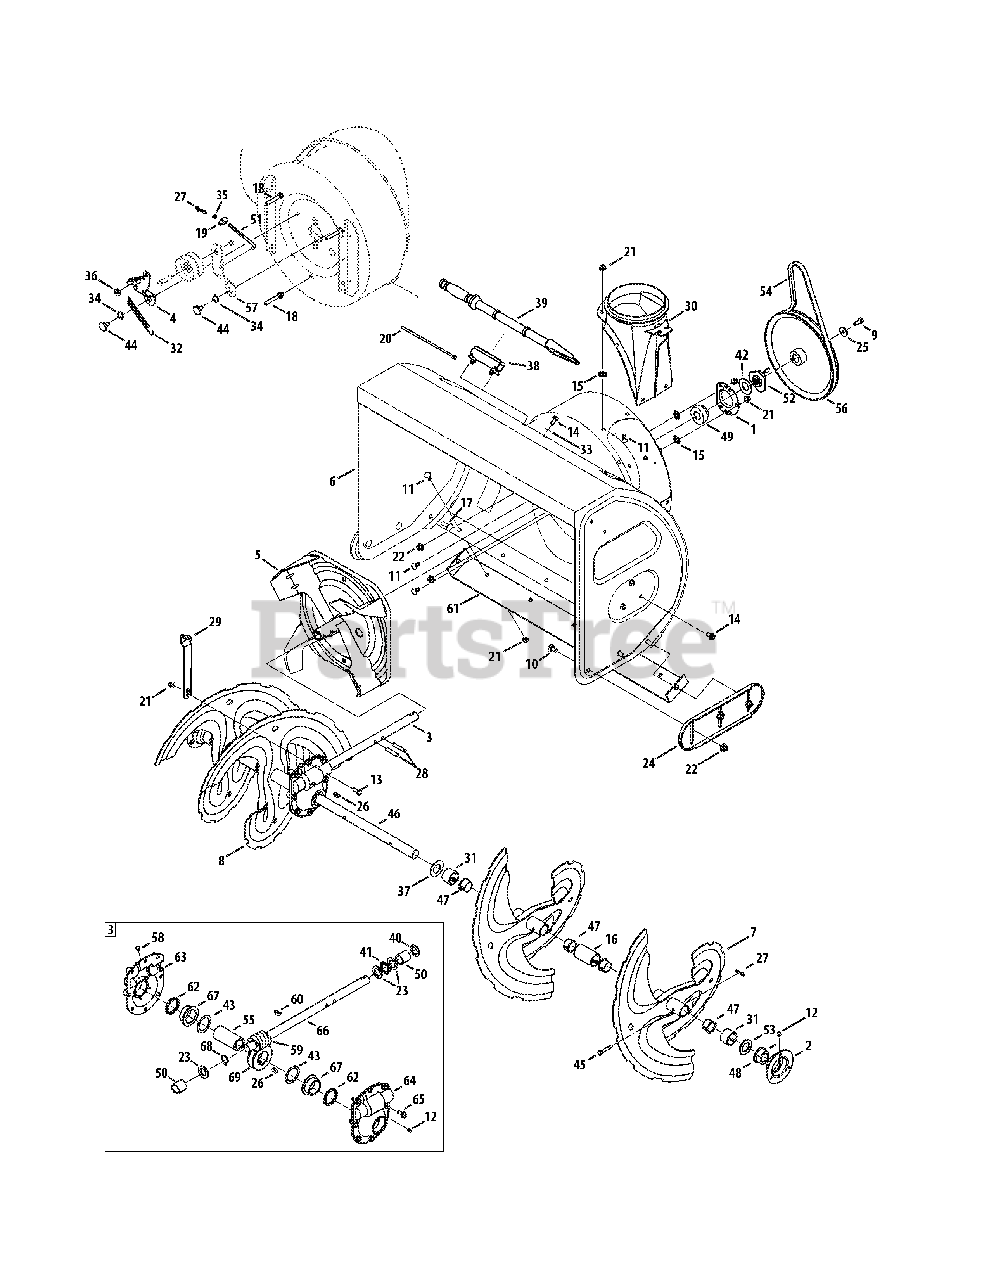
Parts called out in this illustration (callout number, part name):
1	Housing, Bearing
2	Housing, Bearing
3	Gear Box Assembly
4	Bracket Assembly, Auger Brake
5	Impeller, 16"
6	Housing, Auger
7	Spiral Assembly, LH
8	Spiral Assembly, RH
9	Screw, Hex Cap Lock, 5/16-24
10	Screw, Carriage, 3/8-16 x .75
11	Screw, Carriage, 5/16-18 x .75
12	Fitting, Lube
13	Screw, Hex Cap, 5/16-18 x 1.0 Gr5
14	Screw, 5/16-18 x .750
15	Nut, Push
16	Spacer, 1.0 x 1.5 x 2.5 Lg
17	Screw, Carriage, 3/8-16 x 1.00
18	Screw w/Stud, 5/16-18 x .4300
20	Tie Strap
21	Nut, Hex Flange Lock, 5/16-18
22	Nut, Hex Flange Lock, 3/8-16
23	Wash, Flat, .88 ID x .38 OD
24	Skid Shoe
25	Washer, Flat, .34 x 1.5 x .15 Ht.
26	Key, Woodruff, 1/4 x 3/4
27	Pin, Bow-tie Cotter
28	Pin, Spiral, 5/16 x 1.75
29	Bracket, Gear Box Support
30	Adapter, Chute, 6"
31	Spacer, 1.0 x 1.5 x 1.0 Lg
32	Spring, Extension
33	Washer, Flat, .349 x .879 .063
34	Washer, Wave, .625 x .885 x .015
35	Jam Nut, 5/16-18
36	Washer, .344 x .75 x .12
37	Washer, 1.01 x 1.86 x .06
38	Clip, Mounting
39	Tool, Clean-out
40	Seal, Oil
41	Bearing, Thrust
42	Washer, Flat, .76 x 1.49 x .06
43	Wash, Flat, 1.52ID x 2.0 OD
44	Screw, Shoulder, .625 x .17
45	Pin, Shear, .25 x 1.75
46	Shaft, Spiral
47	Bushing, Flange,
48	Bearing, Flange w/Flats
49	Bearing, Self Aligning
51	Rod, Auger Idler
52	Adapter, Pulley w/Pins
53	Spacer, 1.004 x 1.375 x .25
54	V-Belt, 1/2 x 42
55	Shaft, Gear, Worm
56	Pulley, Auger Drive, 10.0
57	Bracket, Auger Idler
59	Gear, Worm
60	Key, Hi Pro, 3/16 x 3/4
61	Plate, Shave
63	Hsg, Ass’y, Auger RH (Incl. Ref. 62 & 67)
64	Hsg, Ass’y, Auger LH (Incl. Ref. 62 & 67)
65	Screw, LD, 5/16-18 x .750
66	Shaft, Drive, Auger
67	Flange Bearing
68	External, Retaining, Ring
69	Gear, Worm, LH
